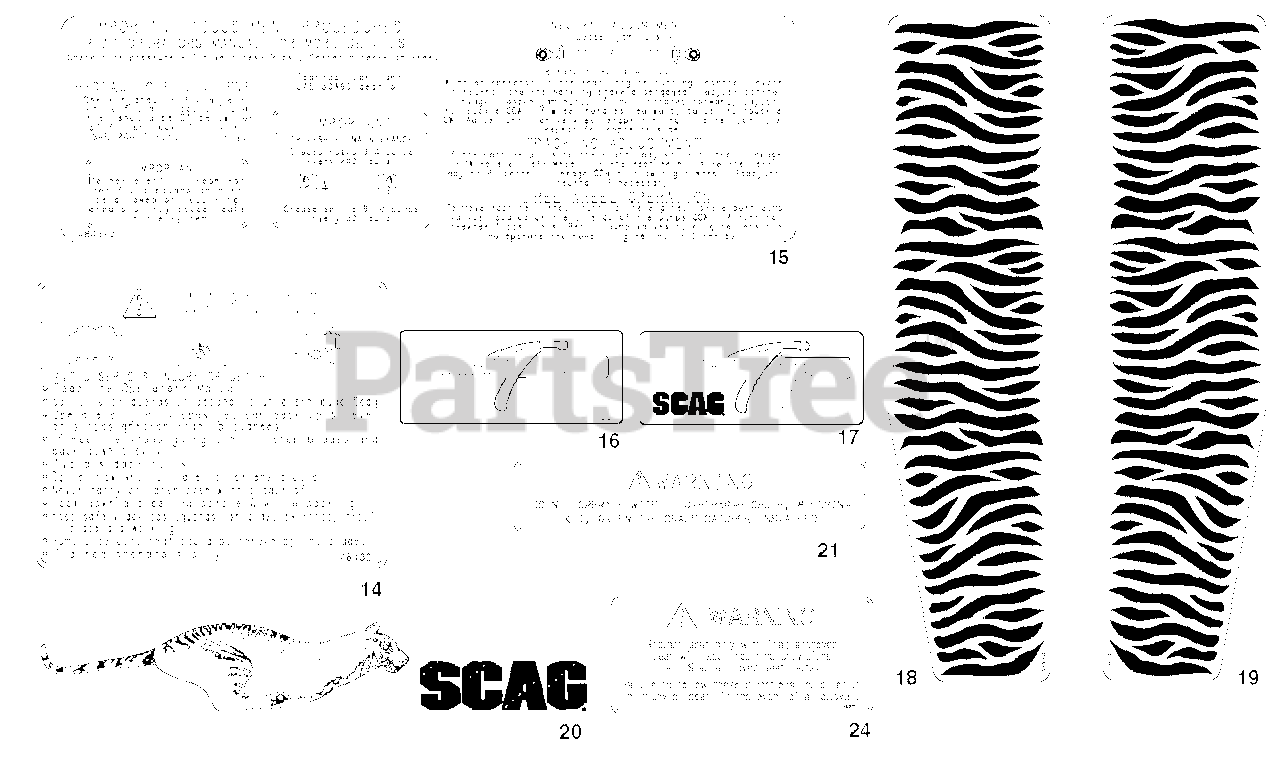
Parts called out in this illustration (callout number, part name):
14	Decal, Fuel Tank Warning
15	Decal, STT Adjustments
16	Decal, Turf Tiger
17	Decal, Turf Tiger
18	Decal, Stripes-RH
19	Decal, Stripes-LH
20	Decal, Tiger
21	Decal, Warning
24	Decal, Seat Replacement
